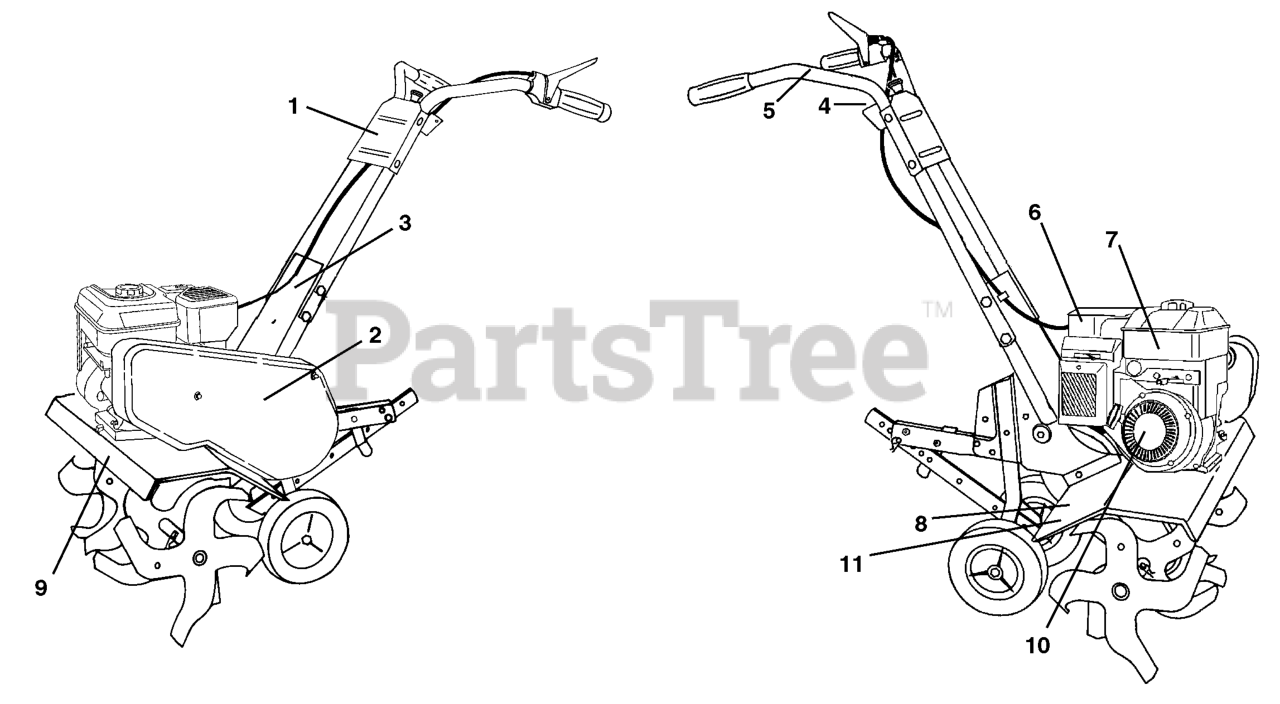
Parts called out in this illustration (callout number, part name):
1	Decal, Logo
2	Decal, Logo
3	Decal, HP, Reverse
4	Decal, Reverse, Tine Control
5	Decal, Hand Placement
6	Decal, Eng. Tiller
7	Decal, OHV. N-I/C
8	Decal, Tine Shield Wrng. Dom
9	Decal, Hvy Duty
10	Decal, Rewind Intek
11	Decal, Warning, Rotating Tines
11	Manual, Owner's (English)
11	Manual, Owner's (Spanish)
